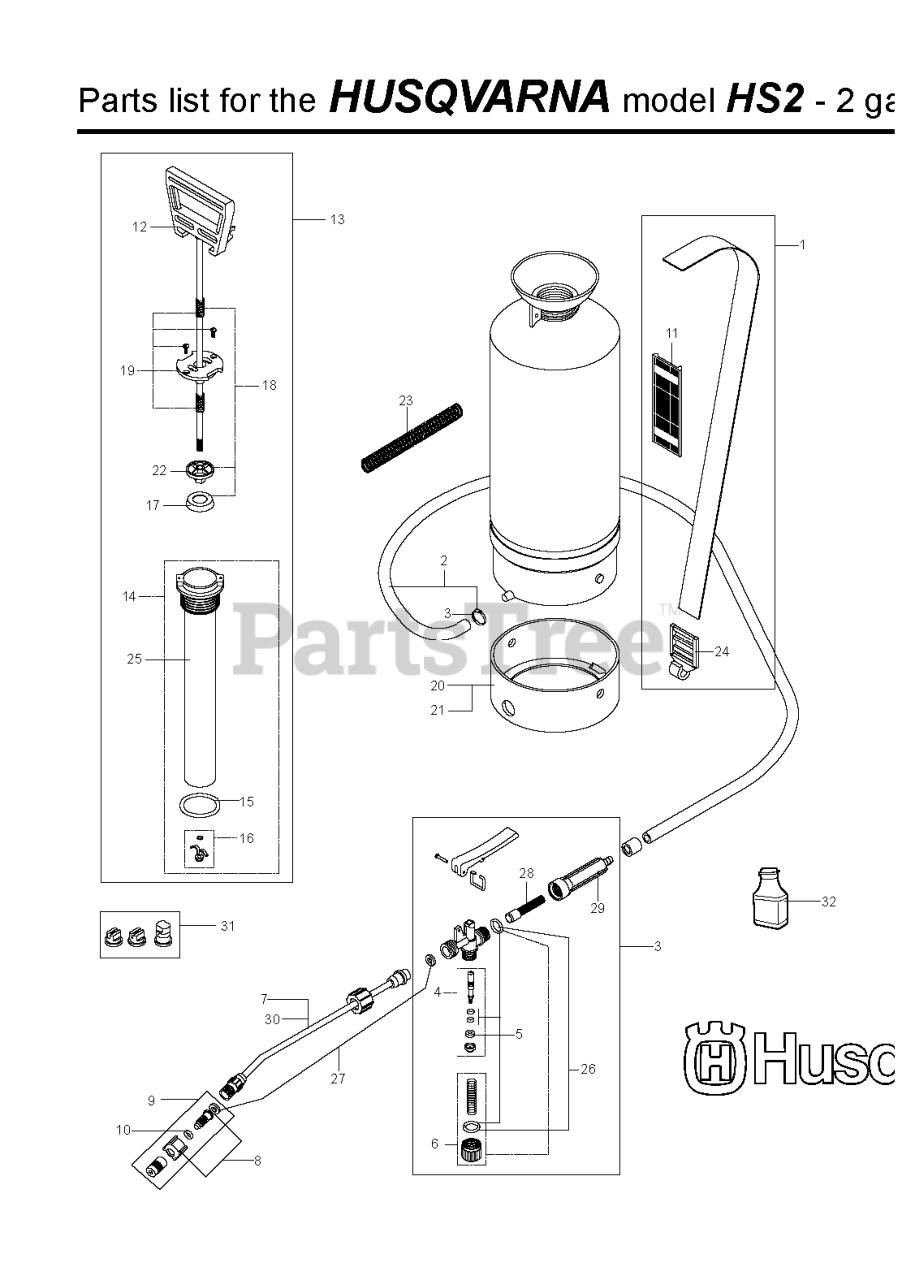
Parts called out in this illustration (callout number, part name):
1	SHOULDER STRAP ASSEMBLY
2	HOSE AND 2 HOSE CLAMPS
3	COMP SPRAY PISTOL WBUILTNFILTE
4	SPINDLE SET
5	SPINDLE O-RING SET
7	BRASS SPRAY WAND 20"
8	NOZZLE HOLDER
9	ADJ BRASS NOZZLE WITH HOLDER
10	SPRAY TIP O-RING SET
11	SHOULDER PAD
12	PUMP HANDLE ORANGE
13	PUMP MODULE COMPLETE ORANGE
14	PUMP TUBE COMPLETE
15	LARGE PUMP O-RING
16	CHECK VALVE ANTENNA & O-RING
17	PUMP PLUNGER NYTRIL
18	PUMP PLUNGER ASSY SET
19	PUMP TOP AND SCREW SET
20	BASE PLASTIC HS2 GREY
21	BASE PLASTIC FOR HS4 GREY
22	PISTON SEAT
23	HOSE SPRING FR COMPRESSION SPR
26	O RING FOR PLUG
27	WASHER SET FOR GUN & NOZZLE
28	FILTER FOR KIT 18F
29	GRIP HANDLE FOR KIT 18F
30	SPRAY WAND 20" PLASTIC
31	PLASTIC SPRAY TIP SET (2-8004)
32	SILICONE GREASE ALL SPRAYERS
